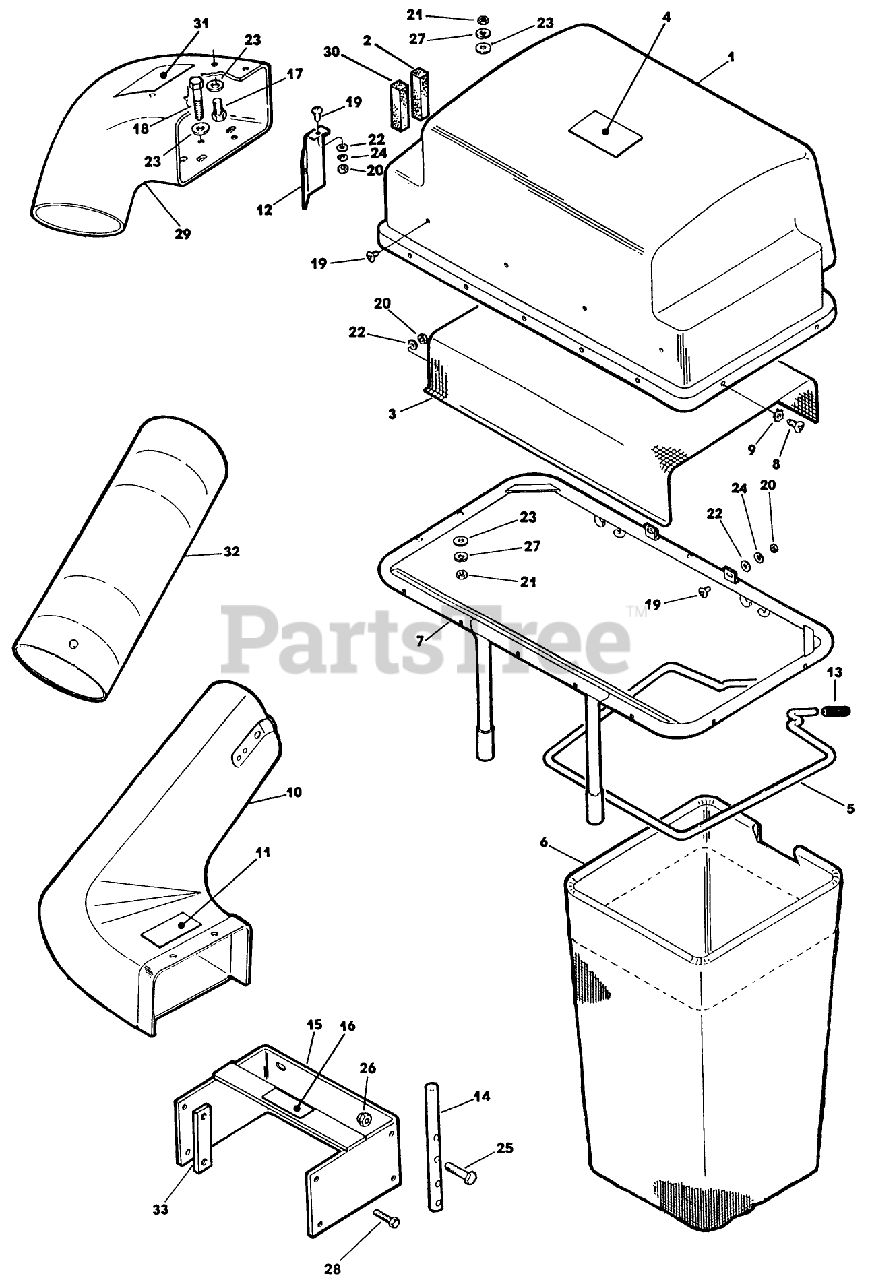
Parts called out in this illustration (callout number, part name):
5	FRAME-GRASS BAG
6	GRASS BAG
14	BAR MOUNTING
21	NUT
26	NUT-LOCKING
28	SCREW-THD ROLL, HWH
29	CHUTE EXT&DECAL AY
32	TUBE
